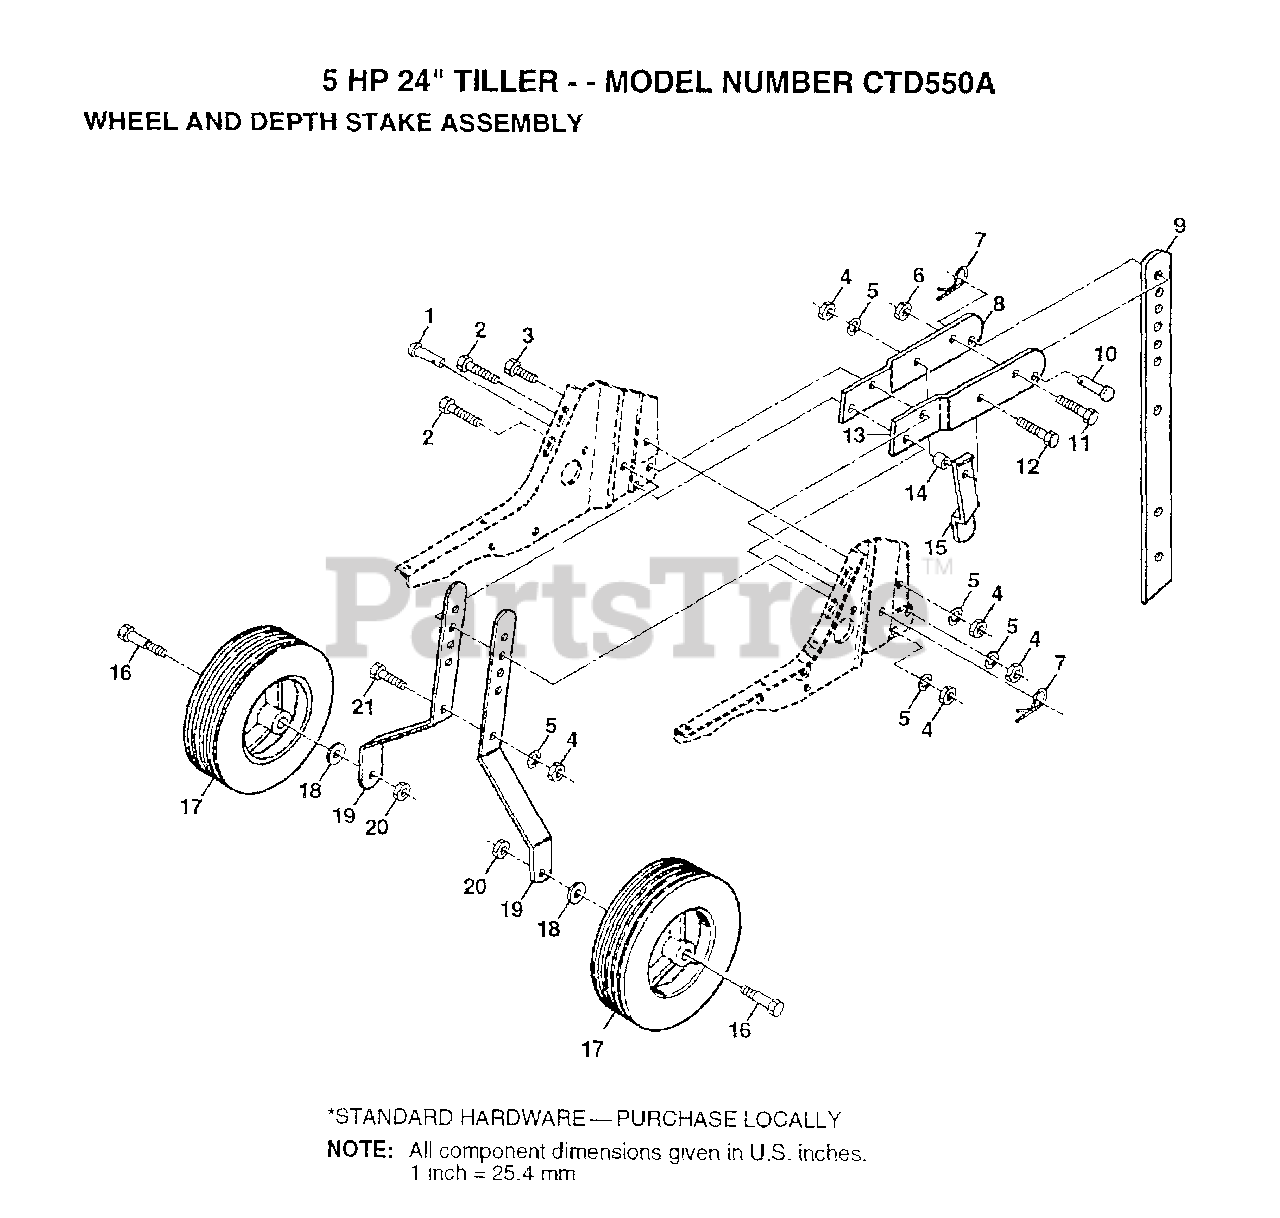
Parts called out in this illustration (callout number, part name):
1	DRILLED RIVET RT
3	BOLT
4	NUT.HEX.5/16-18
5	LOCKWASHER
6	GRIPCO NUT
7	SPRING.RETAINER
11	BOLT.3/8-24X1-1/2
12	BOLT.HEX.5/16-1.5
14	WASHER
15	STAKE SPRING TI
16	BOLT SHOULDER
18	WASHER
